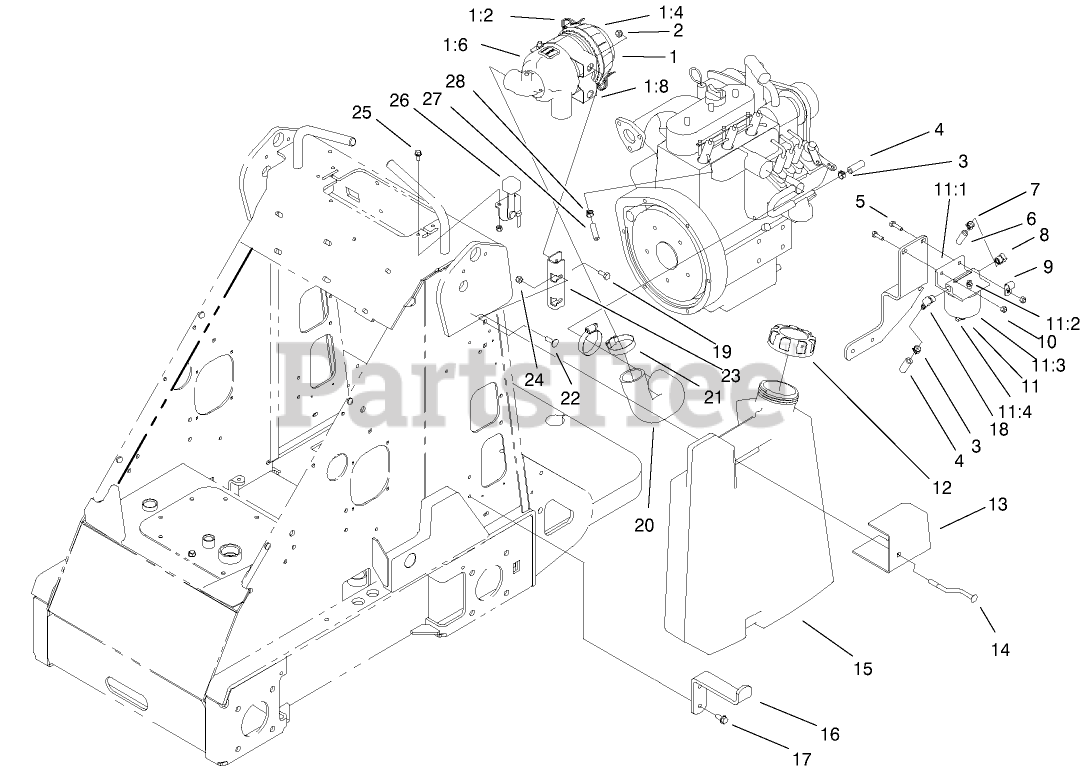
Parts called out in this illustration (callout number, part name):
1	AIR CLEANER ASM
1:2	CLIP-CLEANER, AIR
1:4	COVER
1:6	HOUSING
1:8	MOUNTING BRACKET ASM
2	NUT-LOCK, NI
3	CLAMP-HOSE
4	HOSE-FUEL
5	SCREW-HH
6	HOSE-FUEL
7	CLAMP-HOSE
8	ELBOW
9	CLAMP-R
10	NUT-LOCK, NI
11	SEPARATOR-FILTER / WATER
11:1	HEAD ASM
11:2	VENT-AIR
11:3	ELEMENT-SPIN ON
11:4	VALVE-DRAIN
12	DIESEL FUEL CAP ASM
13	PLATE-MOUNT, LEFT
14	BOLT-MOUNT
15	Fuel Tank ASM
16	MOUNT-BOTTOM, TANK
17	SCREW-HWHTF
18	FITTING-ELBOW
19	SCREW-HH
20	HOSE-CLEANER, AIR
21	CLAMP-HOSE
22	BOLT-CARR
23	MOUNT-CLEANER, AIR
24	NUT-HF
25	SCREW-HHF
26	CONTROL-THROTTLE
27	HOSE-LINE, FUEL
28	CLAMP-HOSE
